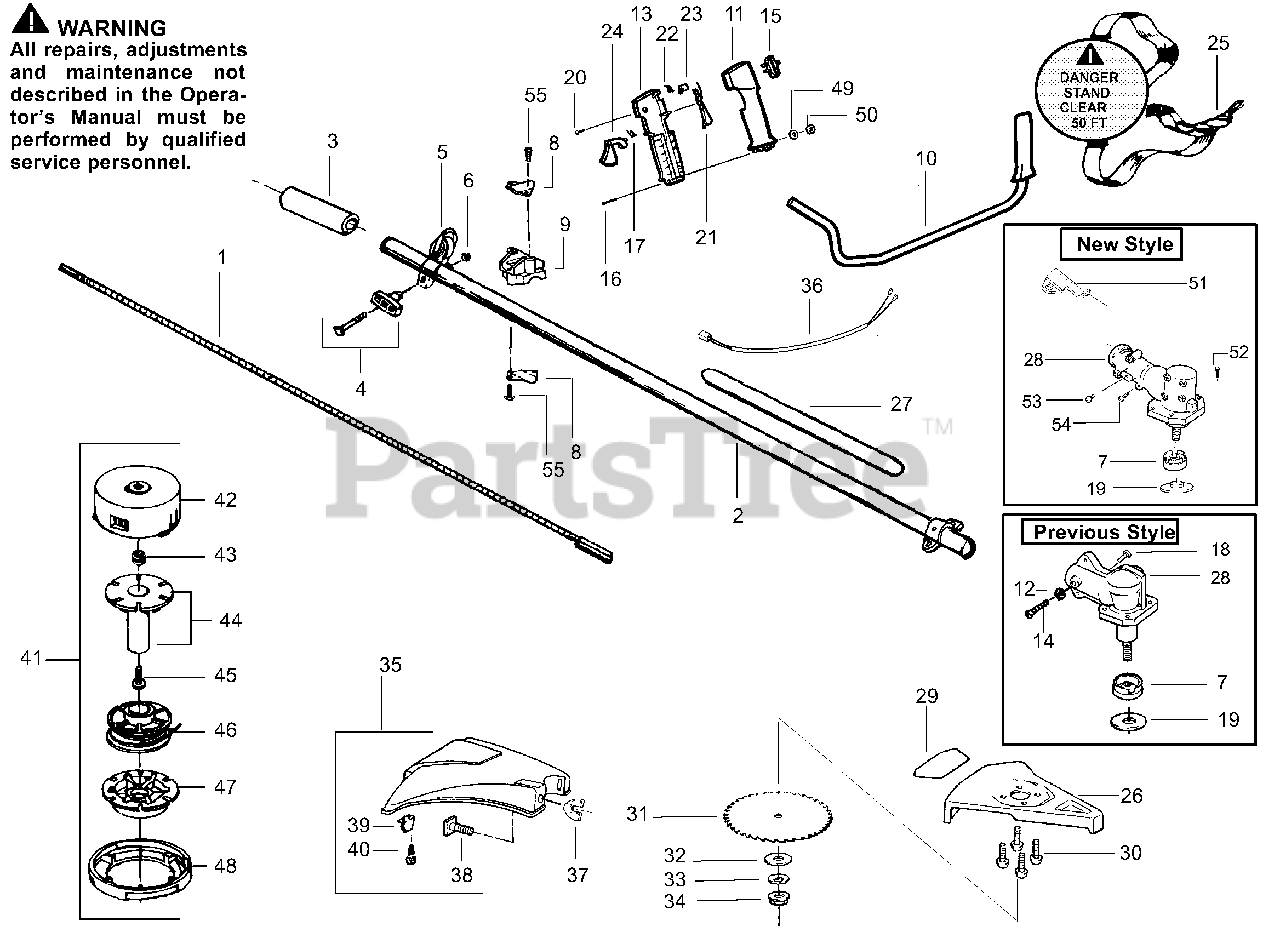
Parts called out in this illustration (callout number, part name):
2	Drive Shaft Housing
3	Pad-Drive Shaft
4	"T" Handle Ass'y.
5	Clamp Harness Assy.
7	Dust Cup
8	Handlebar Bracket
9	Clamp-Handlebar
10	Handlebar Ass'y.
11	Throttle Hsg. Left
12	Lockwasher-Locator
13	Throttle Hsg. Right
14	Screw-Locator
15	Rocker Switch
17	Trigger Spring
18	Screw-Pinch Clamp
19	Washer-Blade Ret.
21	Throttle Lockout
22	Spring Throttle Lock
23	Throttle Lock
24	Throttle Trigger
25	Shoulder Strap
26	Blade Shield Kit
27	Shaft Warning Decal
28	Gear Box Ass'y.
29	Decal Blade Direction
31	Brush Blade
32	Washer-Flat
33	Washer-Spring Bevel
34	Nut-Flange
35	Shield Kit Ass'y.
36	Wire Harness Ass'y.
37	Wingnut
39	Line Limiter
40	Screw
41	Cutting Head Ass'y.
42	Hub Ass'y.
44	Locking Plate Kit
46	Spool w/Line
47	Release Button
49	Washer, Split Lock
51	Bracket-Shield (Type 3)
52	Screw (Type 3)
53	Screw (Type 3)
54	Screw (Type 3)
